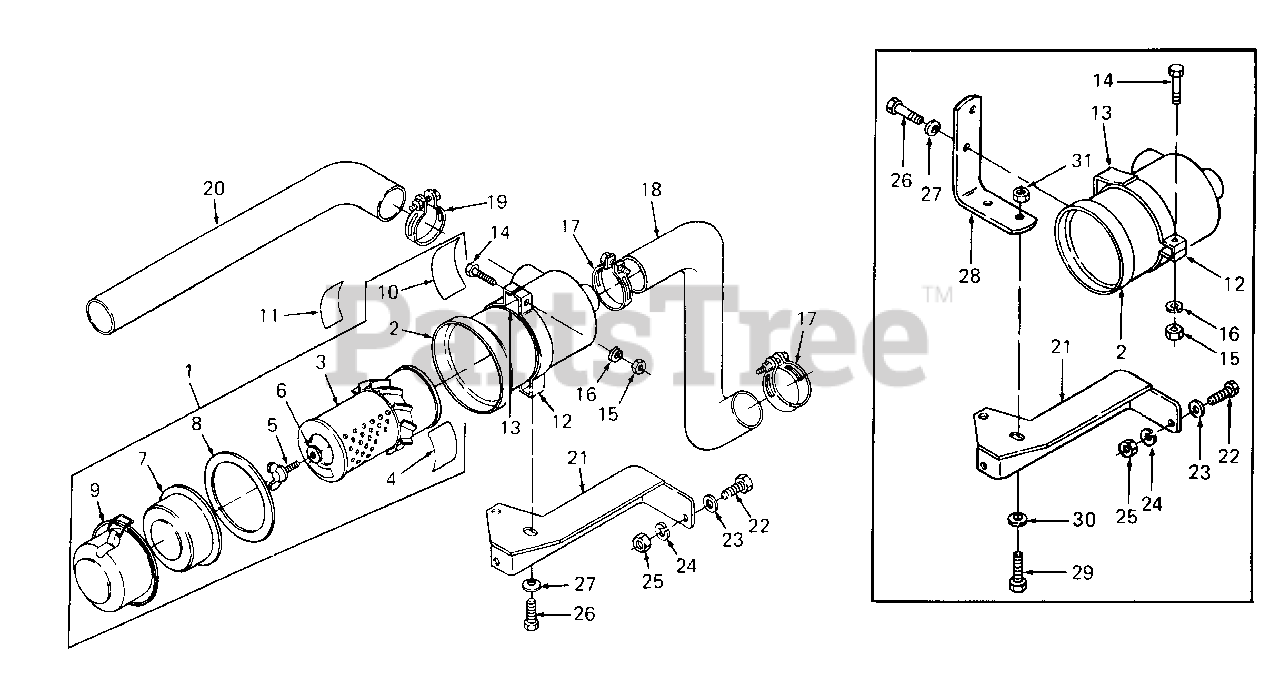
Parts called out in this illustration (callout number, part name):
1	Air Cleaner Assy
2	Body, Air Cleaner
3	Element, Air Cleaner
4	Label, Air Cleaner Element
6	Washer w/Rubber
7	Cover, Baffle
8	Gasket, Air Cleaner Cover
9	Cover, Air Cleaner
10	Label, Air Cleaner
11	Label, Ether Caution
12	Band, Air Cleaner
16	Washer, Spring
17	Clamp, Hose
18	Hose, Carburetor Inlet
19	Clamp, Hose
20	Hose, Air Intake
21	Bracket, Air Cleaner Mtg
22	Screw, Hex Cap, 5/16-18 X .75 Lg GR5
23	Washer, Flat, .344 X 1.5 X .105 Thk
24	Washer, Lock, 5/16
25	Nut, Hex, 5/16-18 GR5
26	Screw, Hex Cap, M8-1.25 X 20 mm GR5
27	Washer, Bell, .345 X .88 X .060 Thk
28	Bracket, Air Cleaner
29	Screw, Hex Cap, 5/16-18 X .50 Lg GR5
30	Washer, Bell, .345 X .88 X .060 Thk
31	Nut, Hex Center Lock, 5/16-18 GR5
